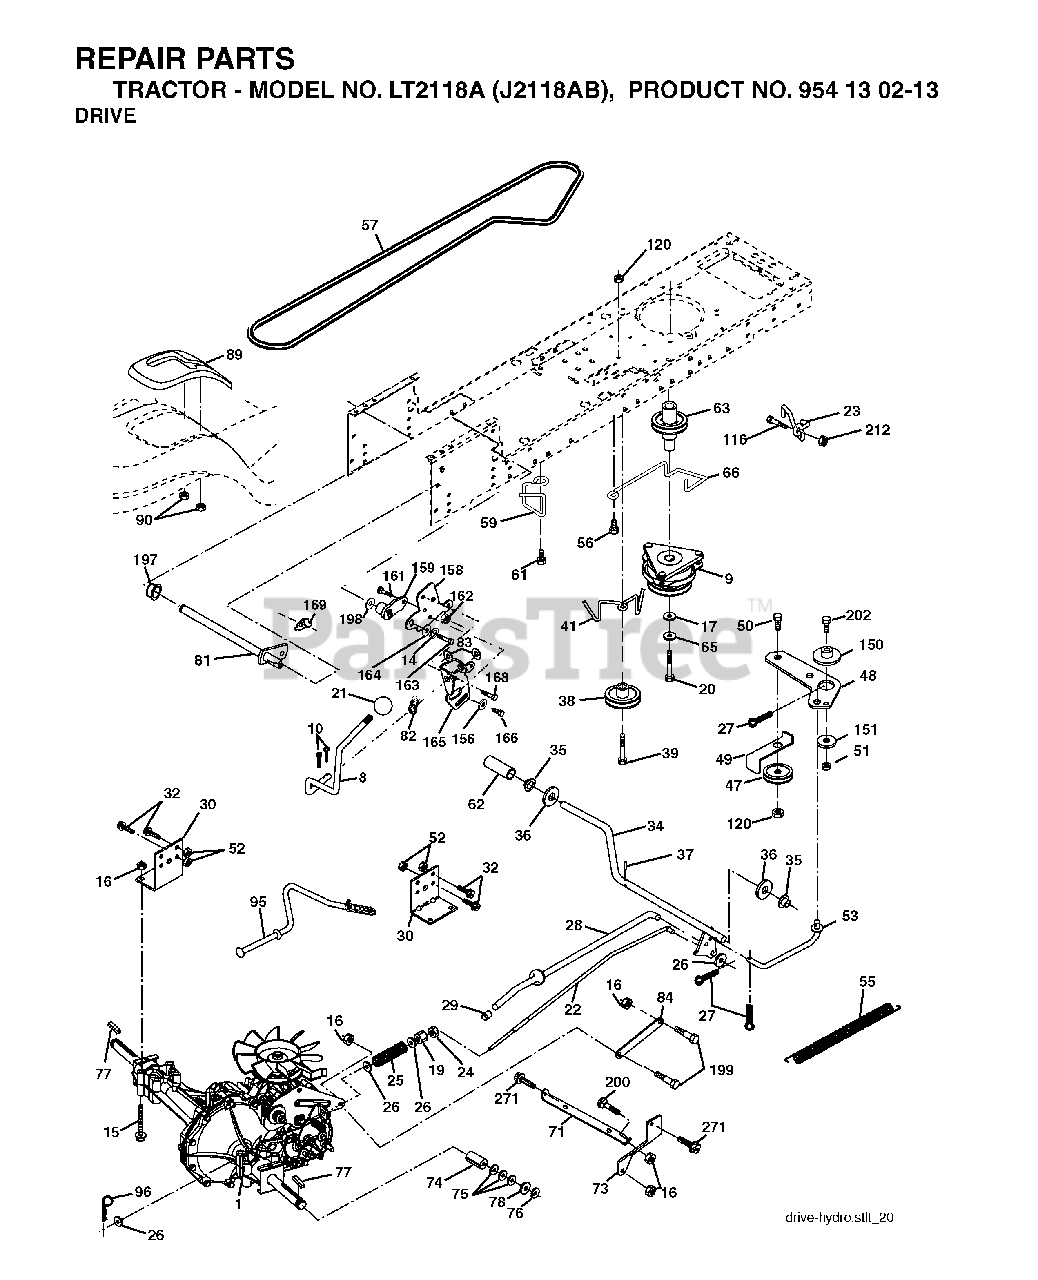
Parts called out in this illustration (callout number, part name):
8	ROD SHIFT FENDER ADJUST STLT
10	PIN COTTER
14	LOCKWASHER
15	BOLT HEX 5/16-18 GR 5
16	NUT.71038.31-18.HEX.NYLOCK
19	NUT
20	BOLT HEX 7/16-20X4-1/4"
21	PISTOL KNOB
22	ROD BRAKE HYDRO
23	BRKT ASM MTNG
24	NUT
25	SPRING ROD LT
27	COTTER PIN
28	ROD, PARKING BRAKE
29	PLUNGER CAP
30	BRKT, TRNSXLE MNT 20"
32	BOLT
34	SHAFT, FOOT PEDAL
35	BEARING.NYLON
36	WASHER LT
37	DRIVE PIN
38	PULLEY IDLER COMPOSITE
41	KEEPER, BELT IDLER
47	IDLER PULLEY
48	BELLCRANK, CLUTCH
49	RETAIN BELT
50	BOLT.3/8-16X1.50
51	LOCKNUT
52	LOCKNUT
53	LINK, CLUTCH LT
55	SPRING, RETURN LT
56	SCREW.3/8-16
57	DRIVE BELT, LTH & YTH TRACTORS
59	KEEPER, BELT CENTER
61	SCREW 3/8-16X.875
62	PEDAL COVER T
63	PULLEY- ENGINE
65	LOCKWASHER
66	KEEPER BELT ENGINE
71	STRAP TORQUE LH HYDRO
73	STRAP TORQUE RH HYDRO
74	SPACER AXLE
76	E-RING LT
77	SQUARE KEY
81	SHAFT ASM CROSS TAPERED
82	SHIFT SPRING
83	WASHER
84	LINK TRANSAXLE
95	CONTROL ASM. BYPASS HYDRO
96	RETAINER M
116	BOLT D
120	NUT LOCK FLG 3/8-16 UNC
150	SPACER, RETAINER
151	WASHER 12/32X2X10GA
156	WASHER.SRRTD.5/16
158	BRACKET
159	HUB.SHIFT
161	BOLT
162	NUT.CROWNLOCK.1/4
164	WASHER LT
165	RP BRACKET
168	BOLT.SHOULDER.5/16-18X
169	PLATE.FASTENING.CROSS.SHAFT
197	NYLINER SNAP 5/8" ID
198	WASHER.NYL.7/8IDX.105"HYD CR
199	BOLT SHOULDER 5/16-18 UNC
200	BOLT
202	BOLT
212	NUT
271	SCREW, 3/8-16X3/4
